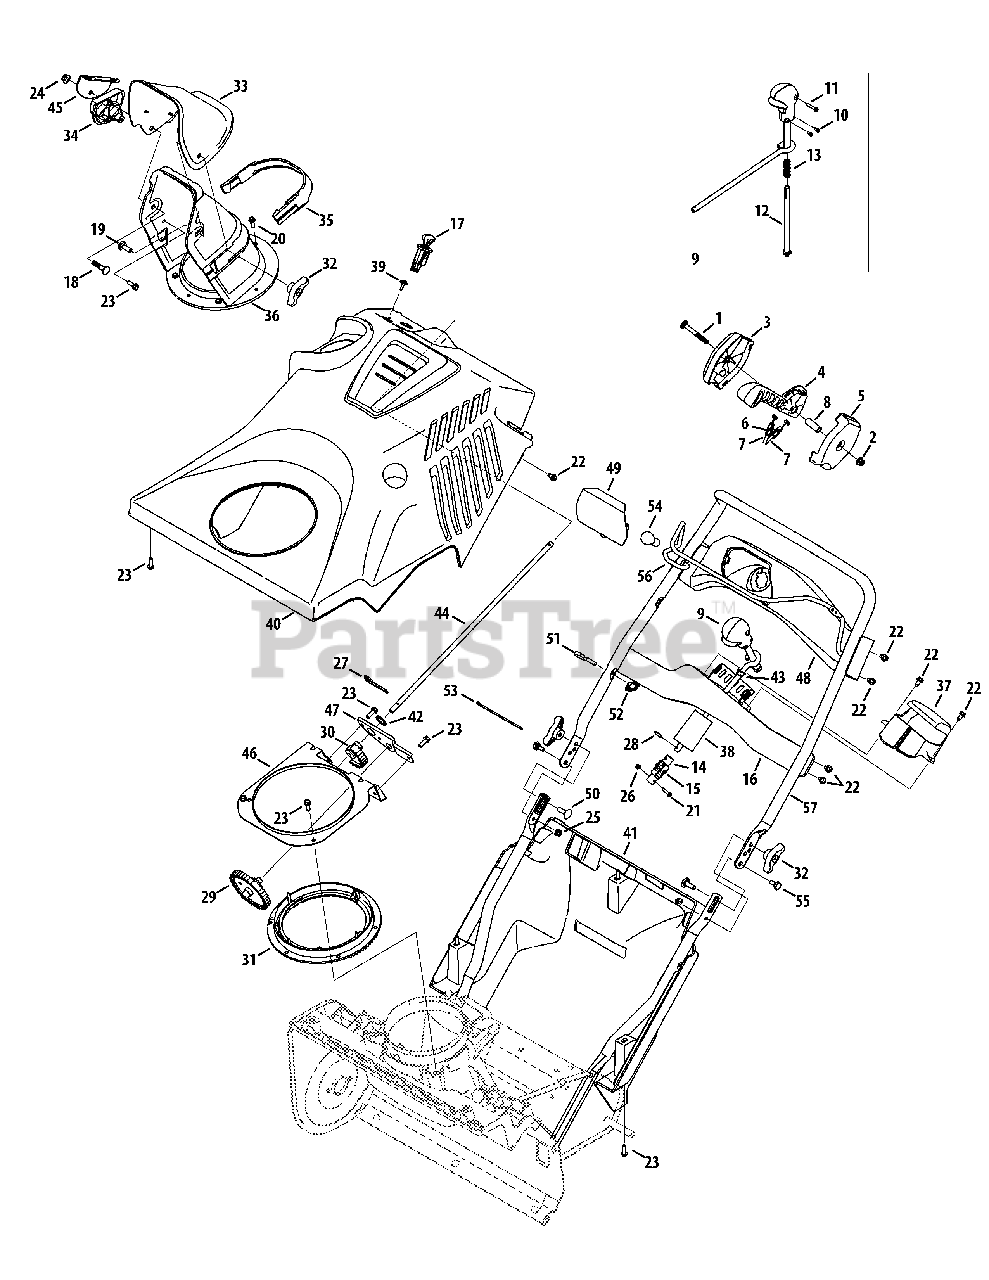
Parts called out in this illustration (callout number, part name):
1	Carriage Bolt, 5/16-18 x 2.5
2	Flange Lock Nut, 5/16-18
3	Chute Control Panel
4	Cable Handle Guide
5	Chute Control Panel, Inner
6	Cable Clip
8	Spacer, .325 ID x .496 OD x 1.34
9	Chute Control Assembly
10	Screw, #6 x .375
11	Screw, #8 x 1.00
13	Spring, .460 OD x 1.469
14	Joint Block Assembly
15	Roll Pin, 3/16 Dia. x 1.1 LG.
16	Indicator Bracket Assembly
17	Ignition Switch Assembly
18	Carriage Bolt, 5/16-18 x 1.00
19	Carriage Bolt, 5/16-18 x 1.00
20	Hex Washer Screw, 1/4 x .750
21	Screw, #8-32 x .875
22	Hex Washer Screw, 1/4-20 x .500
23	Screw, Hi-Lo:1/4-15, 0.75
24	Flange Lock Nut, 5/16-18
25	Flange Lock Nut, 1/4-20
26	Hex Lock Nut, #8-32
27	Cotter Pin
28	Pin, .156 x .875
29	Spur Gear, 40T/11T
30	Spur Gear, 35T
31	Bevel Gear, 95T
32	Wing Knob, 5/16-18
33	Upper Chute
34	Cable Guide
35	Chute Plug
36	Lower Chute
37	Chute Cover
38	Grip, 1.18 x 3.33
39	Hex Washer Screw, 10-16 x .625
40	Top Cover
41	Bottom Cover
42	Flat Washer, .75 x 1.00 x .06
43	Plastic Bushing, .380 ID
46	Gear Retainer Bracket
47	Gear Mounting Plate
48	Handle Panel Assembly
49	Handle Panel Lens
50	Carriage Screw, 5/16-18 x 1.00
51	Eye Bolt, 1/4-20
52	Handle Knob, 1/4-20
53	Cable Tie
55	Shoulder Screw, .375 x .148 x 1/4-20
56	Auger Bail
